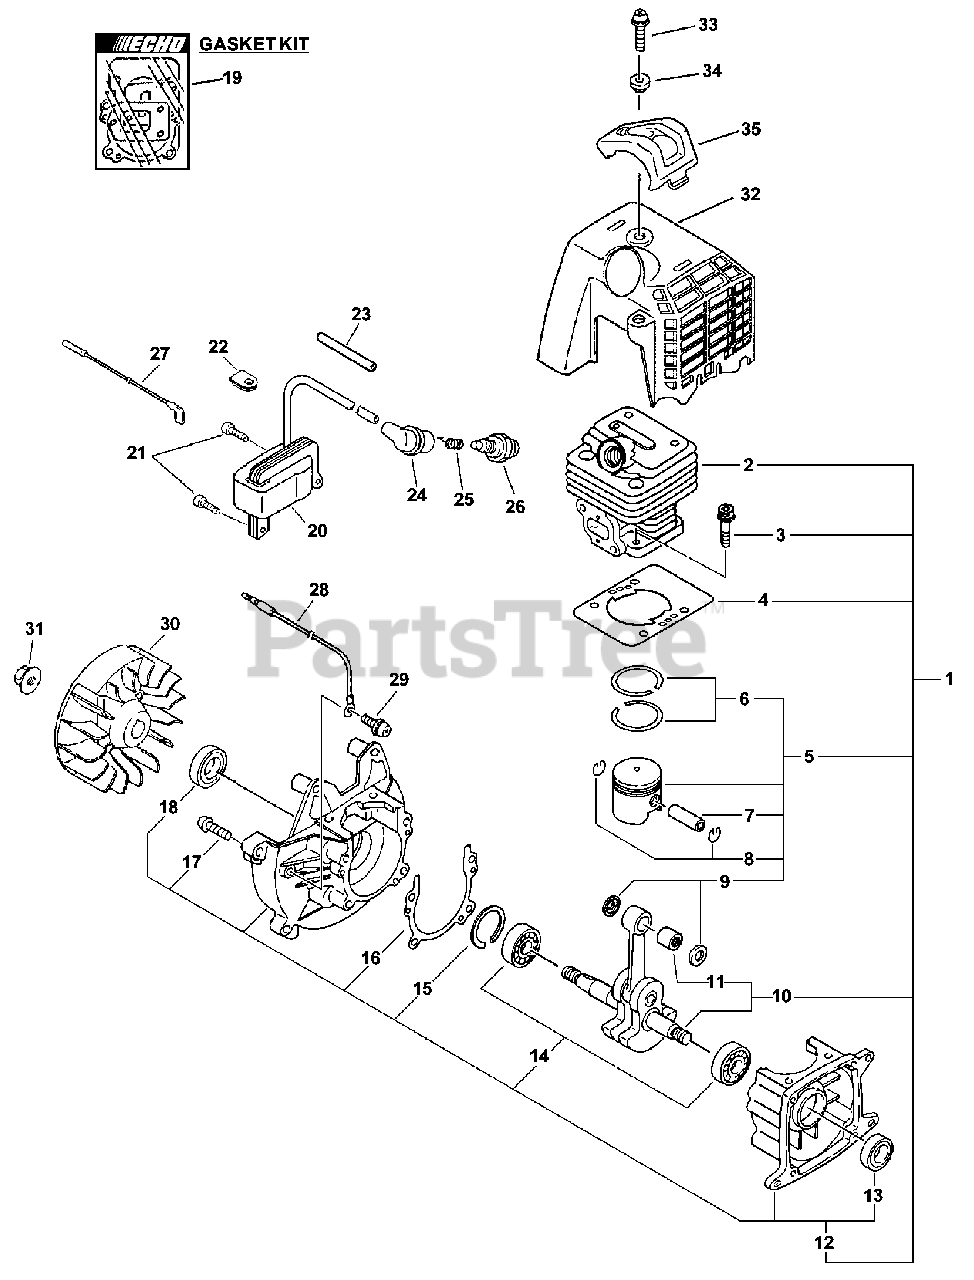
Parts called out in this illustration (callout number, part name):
1	SHORT BLOCK -- SB1061
2	CYLINDER
3	SCREW - 5X22
4	GASKET, CYLINDER
5	PISTON KIT
6	RING, PISTON
7	PIN, PISTON
8	RING, RETAINING
9	SPACER, PISTON
10	CRANKSHAFT ASSY
11	BEARING, NEEDLE - 8
12	CRANKCASE KIT
13	SEAL, OIL
14	BEARING, BALL - 6001C3
15	RING, RETAINING - 28
16	GASKET, CRANKCASE
17	SCREW - 5X25
18	SEAL, OIL - 12
19	GASKET KIT
20	COIL, IGNITION
21	SCREW - 5X16
23	TUBE, INSULATOR
24	CAP, SPARK PLUG
25	TERMINAL, SPARK PLUG CAP
26	SPARK PLUG -- BPM-8Y
26	SPARK PLUG
27	LEAD - IGNITION
28	LEAD - GROUND
29	SCREW - 5X10
30	FLYWHEEL
31	NUT - 8 -- FLANGE
32	COVER, ENGINE - GRAY
33	SCREW - 5X16
34	COLLAR - 5
35	GUARD - TOP
